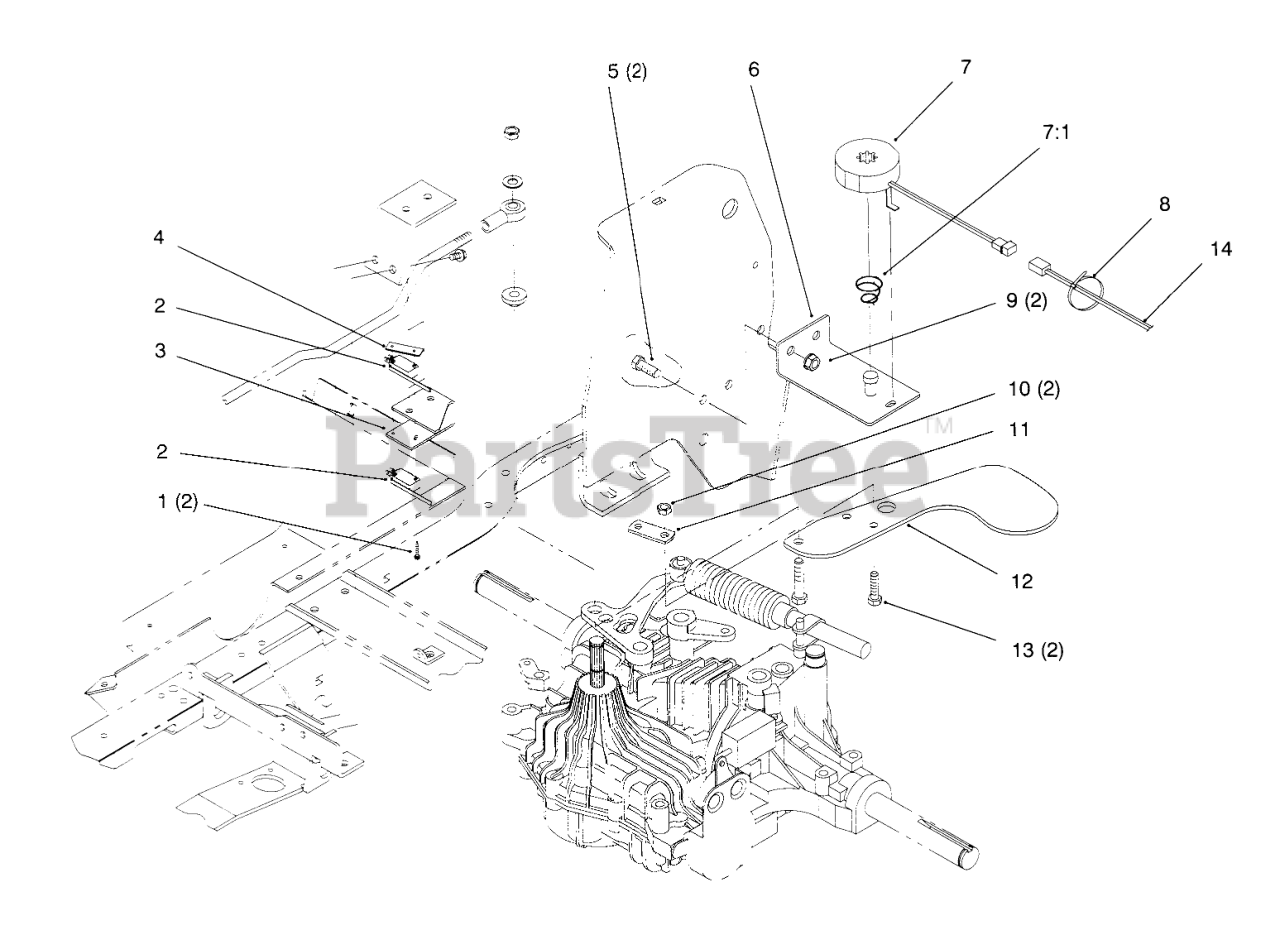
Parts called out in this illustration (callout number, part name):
1	Screw (Only On: 72103)
2	Switch-Micro (Only On: 72103)
3	Bracket-Micro Sw (Only On: 72103)
4	Nut-Speed (Only On: 72103)
5	Screw-HH (Only On: 72103)
6	Cruise Bracket (Only On: 72103)
7	Magnet Assembly (INCL 7: Only On: 72103)
7:1	Spring-Conical (Only On: 72103)
8	Tie Strap (Only On: 72103)
9	Nut-Lock (Only On: 72103)
10	Nut-Lock (Only On: 72103)
11	Clamp-Cruise (Only On: 72103)
12	Arm-Cruise (Only On: 72103)
13	Screw-HH (Only On: 72103)
14	Harness-Wire (Only On: 72103)
